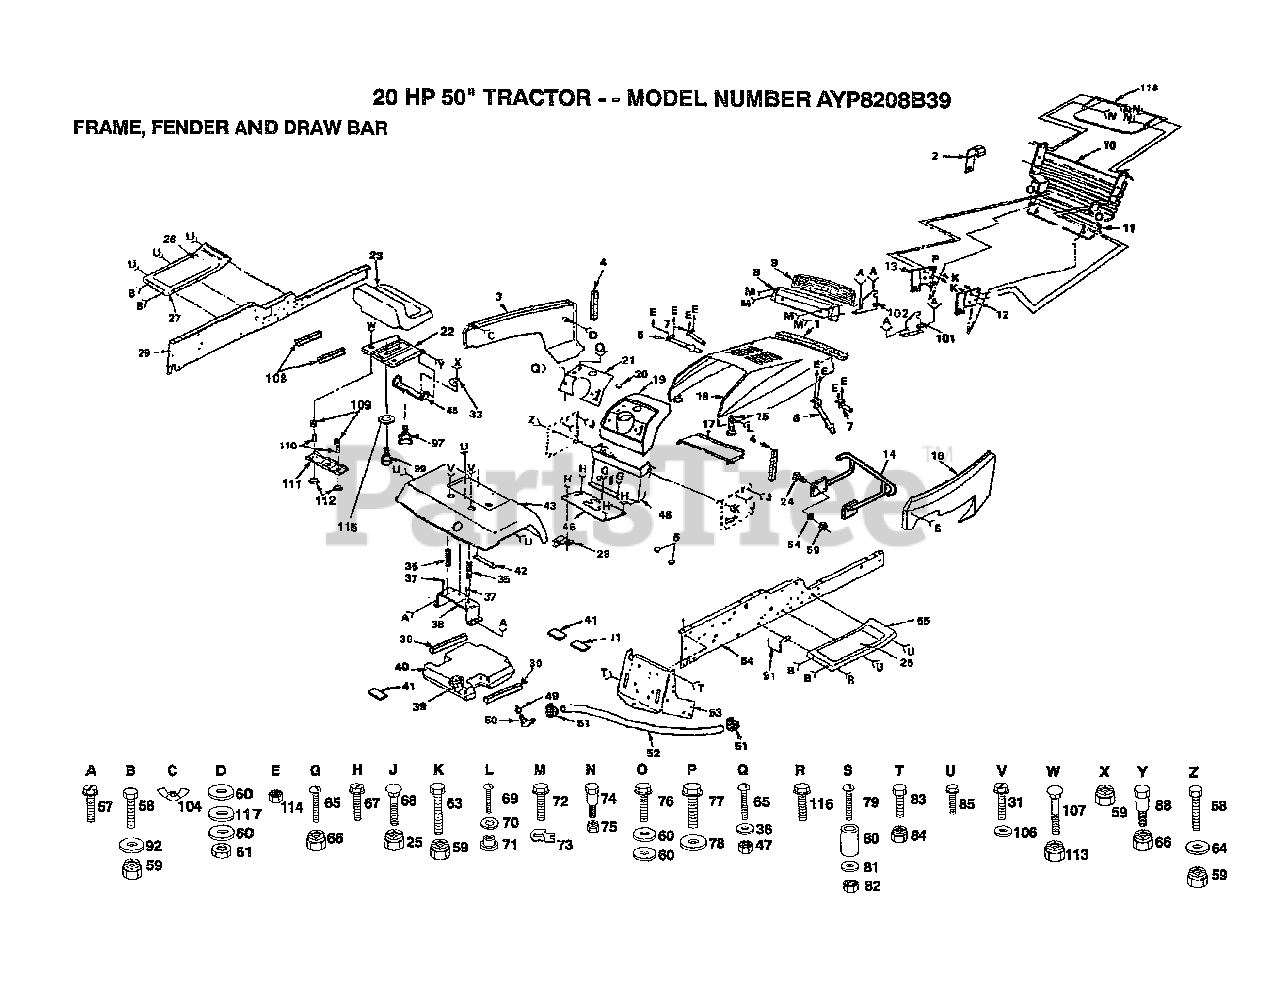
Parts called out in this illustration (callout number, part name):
1	FOAM STRIP T
3	"PANEL,SIDE LH "
4	FOAM STRIP T
5	CAP SPRING
9	LENS LT
12	SUPPORT RH YTH
13	SUPPORT LH YTH
14	BUMPER ASSY.
15	HOOD LATCH T
16	"PANEL,SIDE RH "
20	PLUG-DASH T
24	BOLT
25	NUT
26	FOOTREST PAD
28	"CLIP,INSULATOR"
30	PAD IDLER TI
31	SCREW LT
33	CLIP T
35	SPRING COMPRESSIO
36	WASHER
37	NUT-PUSH YT
38	BRKT.ASM.FENDER
41	PAD-SPACER LT
43	FENDER
46	SADDLE.6SP.GT
48	DASH ASSEMBLY
49	BUSHING OUTLET T
50	STEM.TANK.FUEL
51	HOSE CLAMP
57	SCREW
60	WASHER PM
63	BOLT
64	WASHER
65	SCREW
67	SCREW
68	BOLT
69	SCREW
70	LOCKWASHER
71	WELDNUT
73	"""J"" FASTENER LT"
76	SCREW
77	SCREW
78	WASHER
79	SCREW
80	SPACER LT
81	WASHER
83	BOLT
84	NUT GTV
85	SCREW LT
91	BELT RETAINER GT
92	WASHER
97	"KNOB 1/2"" YT"
99	"BOLT,SHOULDER"
101	SUPPORT RH YTH
102	SUPPORT LH YTH
106	WASHER
108	STRIP FORM
109	SPRING COMPRESSED
110	SPACER SPLIT
111	BRKT SWITCH
112	BUSHING
114	NUT
115	WASHER
116	SCREW GTV
117	WASHER
118	"SHIELD,HEAT"
